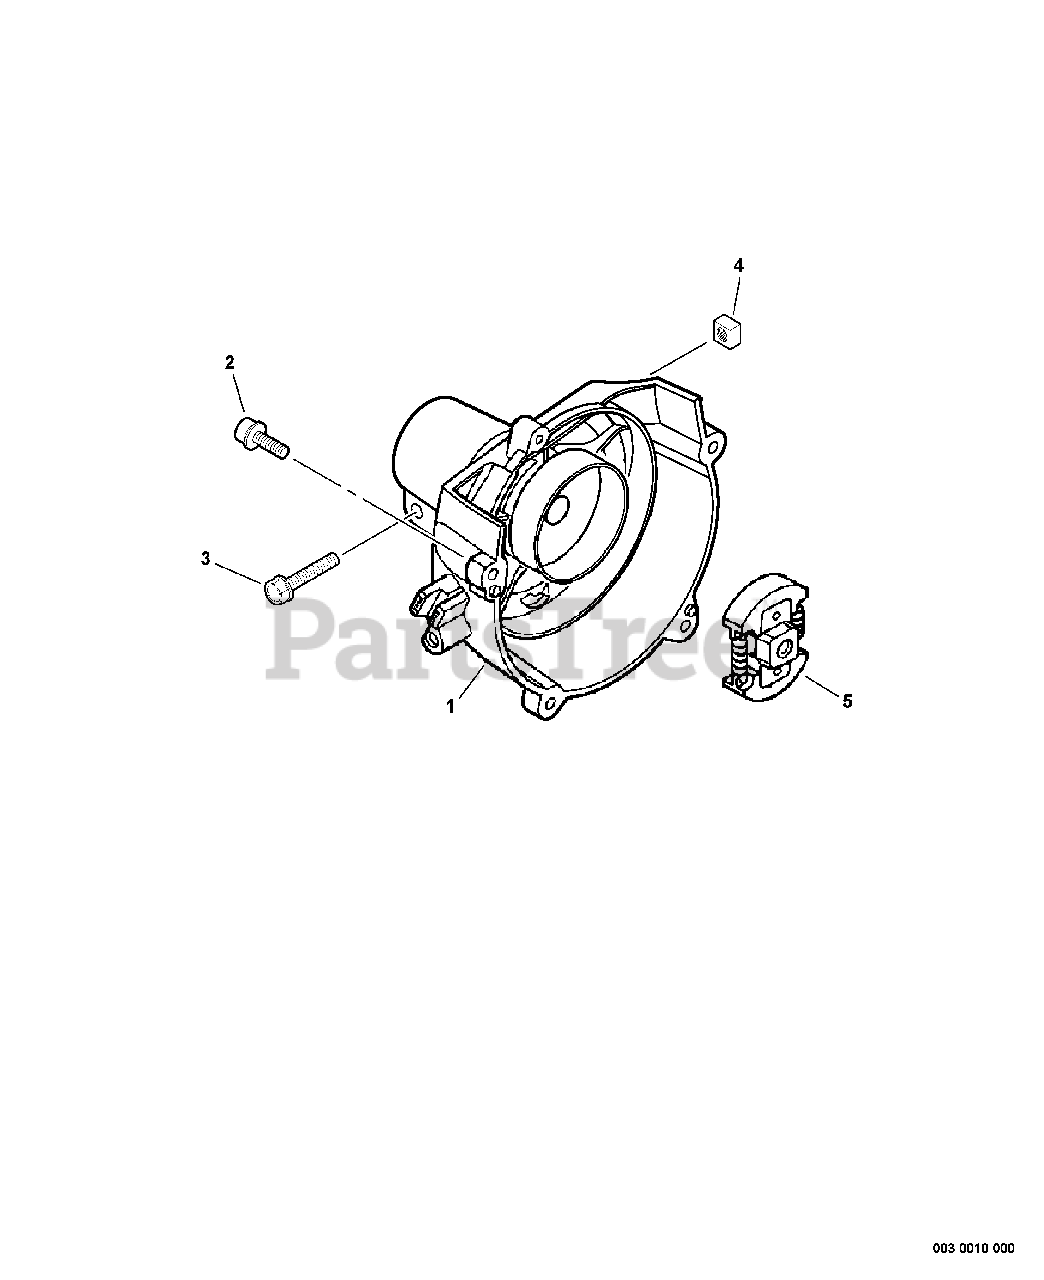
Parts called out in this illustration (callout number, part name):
1	COVER ASSY, FAN
2	BOLT, FLANGE 4×16
3	BOLT 5×28
4	NUT - 5 -- SQUARE
5	CLUTCH ASSY
